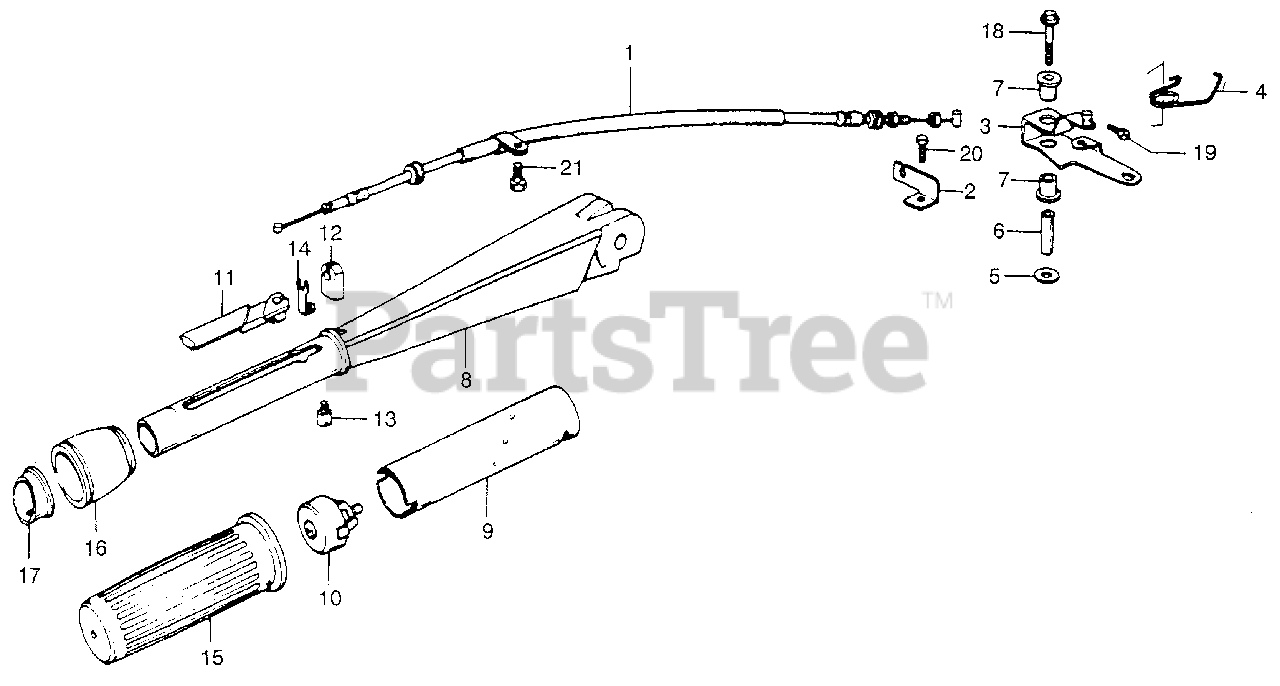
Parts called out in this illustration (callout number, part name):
1	CABLE, THROTTLE
2	HOLDER, CABLE
3	ARM, THROTTLE
4	SPRING, THROTTLE ARM
5	WASHER, PIVOT
6	COLLAR, PIVOT
7	BUSH, SHAFT
8	HANDLEBAR *B9* (ATLANTIS BLUE) (NOT AVAILABLE)
9	PIPE, GRIP
10	NUT, GRIP FRICTION (NOT AVAILABLE)
11	HINGE, THROTTLE WIRE
12	HOLDER, THROTTLE CABLE
13	STOPPER, GRIP PIPE
14	STOPPER, CABLE
15	RUBBER, GRIP
16	COVER, GRIP PIPE (NOT AVAILABLE)
17	GUIDE B, GRIP PIPE
18	BOLT, FLANGE (6X35)
19	BOLT, STRAIGHT SLOT (4X6)
20	BOLT, HEX. (6X12)
21	BOLT, HEX. (6X12)
